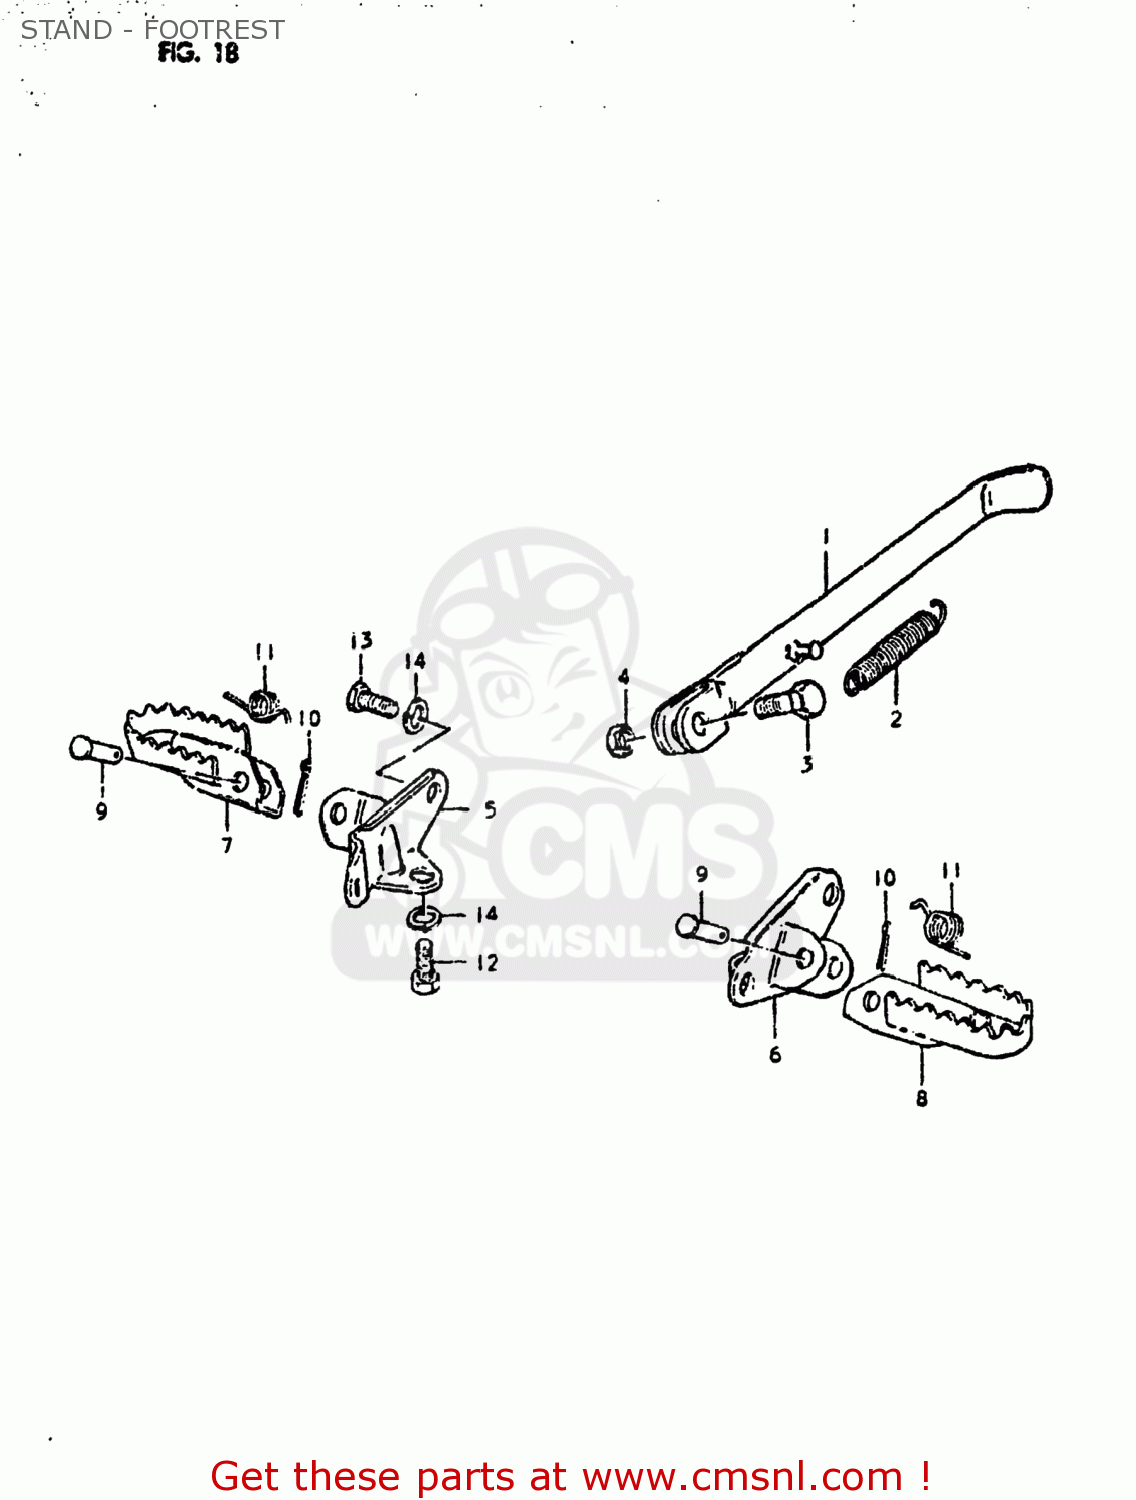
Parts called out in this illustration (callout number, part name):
1	STAND,PROP
2	SPRING
3	BOLT(10X30)
4	NUT
5	HOLDER,FRONT FOOTREST,RIGHT
6	HOLDER,FRONT FOOTREST
7	FOOTREST,FRONT
8	FOOTREST
9	PIN
10	PIN 20X20
11	SPRING
12	BOLT
13	BOLT 8X16
14	WASHER,LOCK,8.
